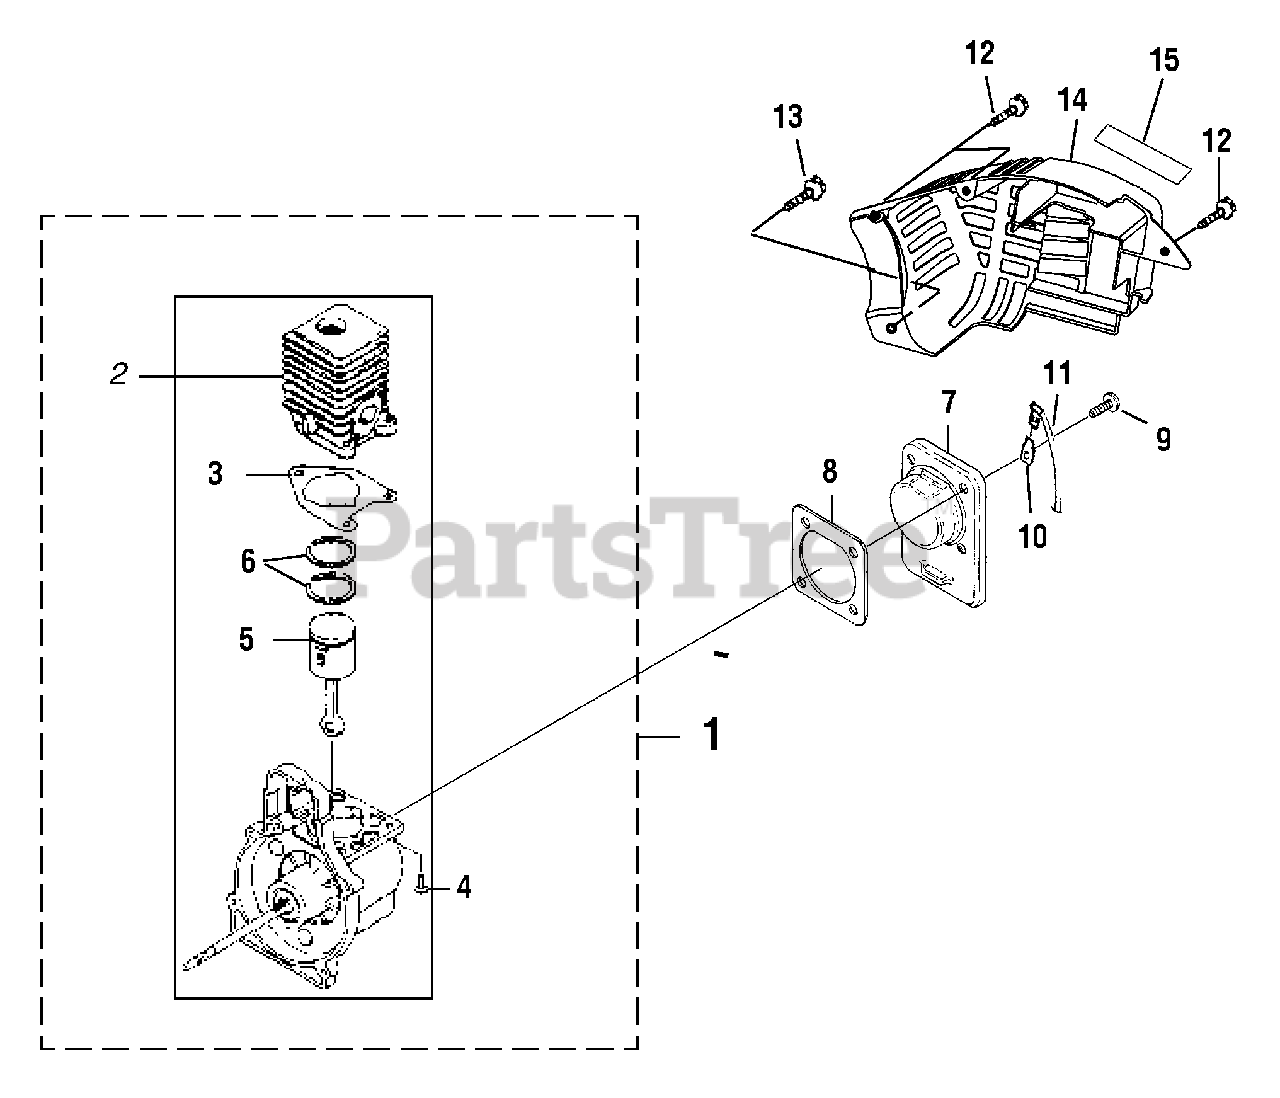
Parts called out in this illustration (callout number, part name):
1	SHORT BLOCK (30cc)
2	30cc CYLINDER
3	CYLINDER GASKET
4	SCREW (12-24 x 3/4 in. TORX PAN HD.)
5	30cc PISTON AND ROD
6	PISTON RING.
7	CRANKCASE COVER.
8	CRANKCASE GASKET
9	SCREW (10-24 x 9/16 in. PAN HD.)
10	MALE TAB.
11	LEAD-GROUND TO HANDLE.
12	SCREW (#8 x 1/2 in. PAN HD.)
13	SCREW (#10 x 3/4 in. TORX TRUSS HD.)
15	ZIP START DECAL
